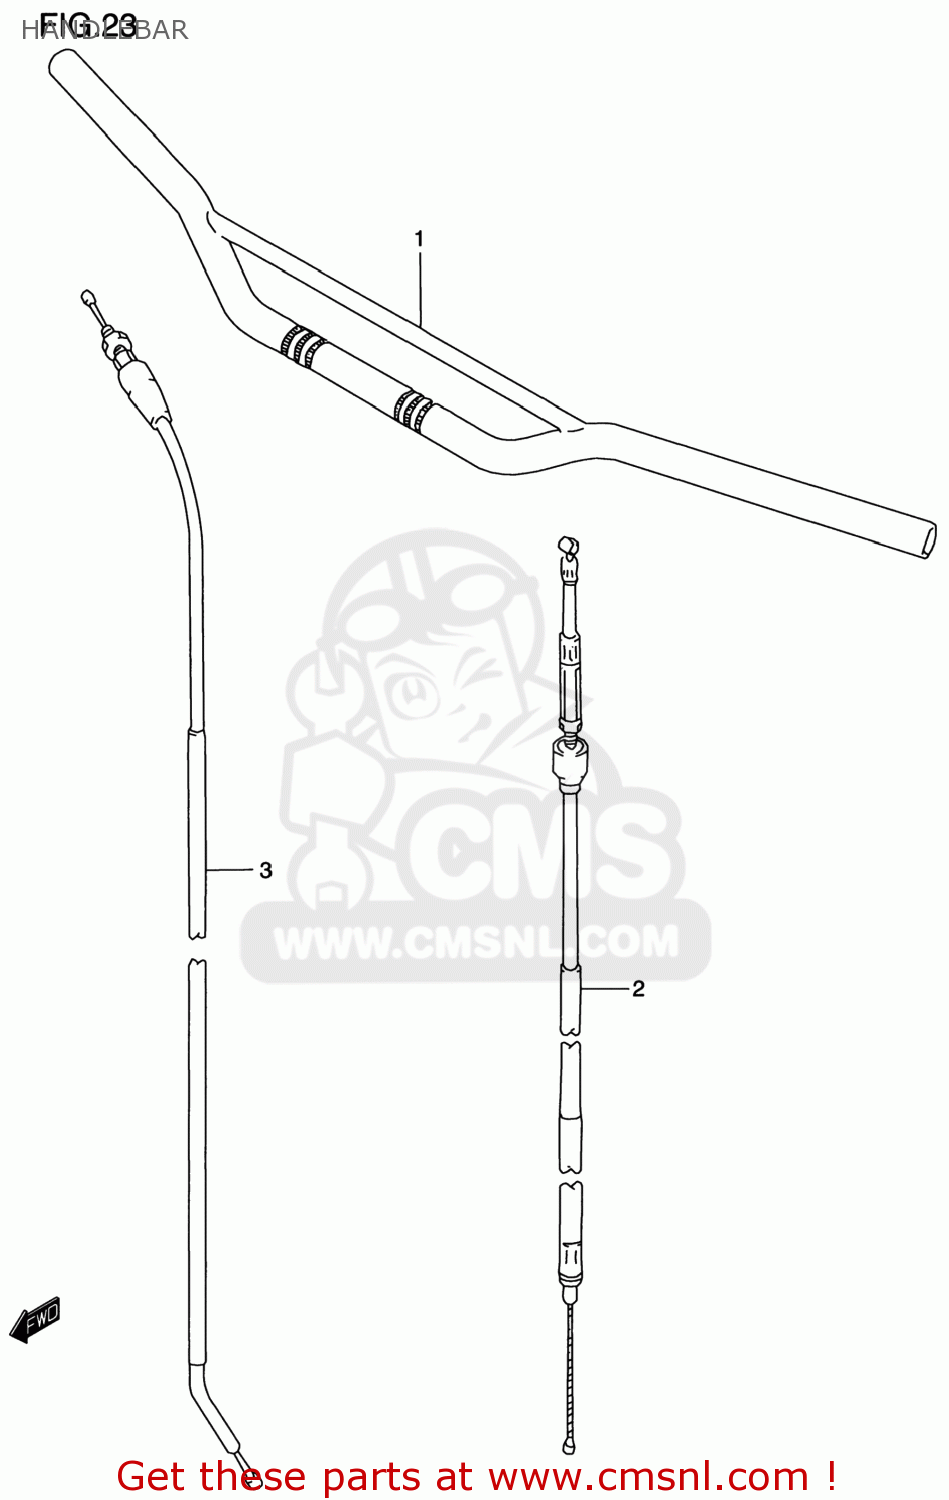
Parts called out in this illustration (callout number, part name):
1	HANDLEBAR(SILVER)
2	CABLE ASSY,CLUTCH
3	CABLE ASSY,THROTTLE
